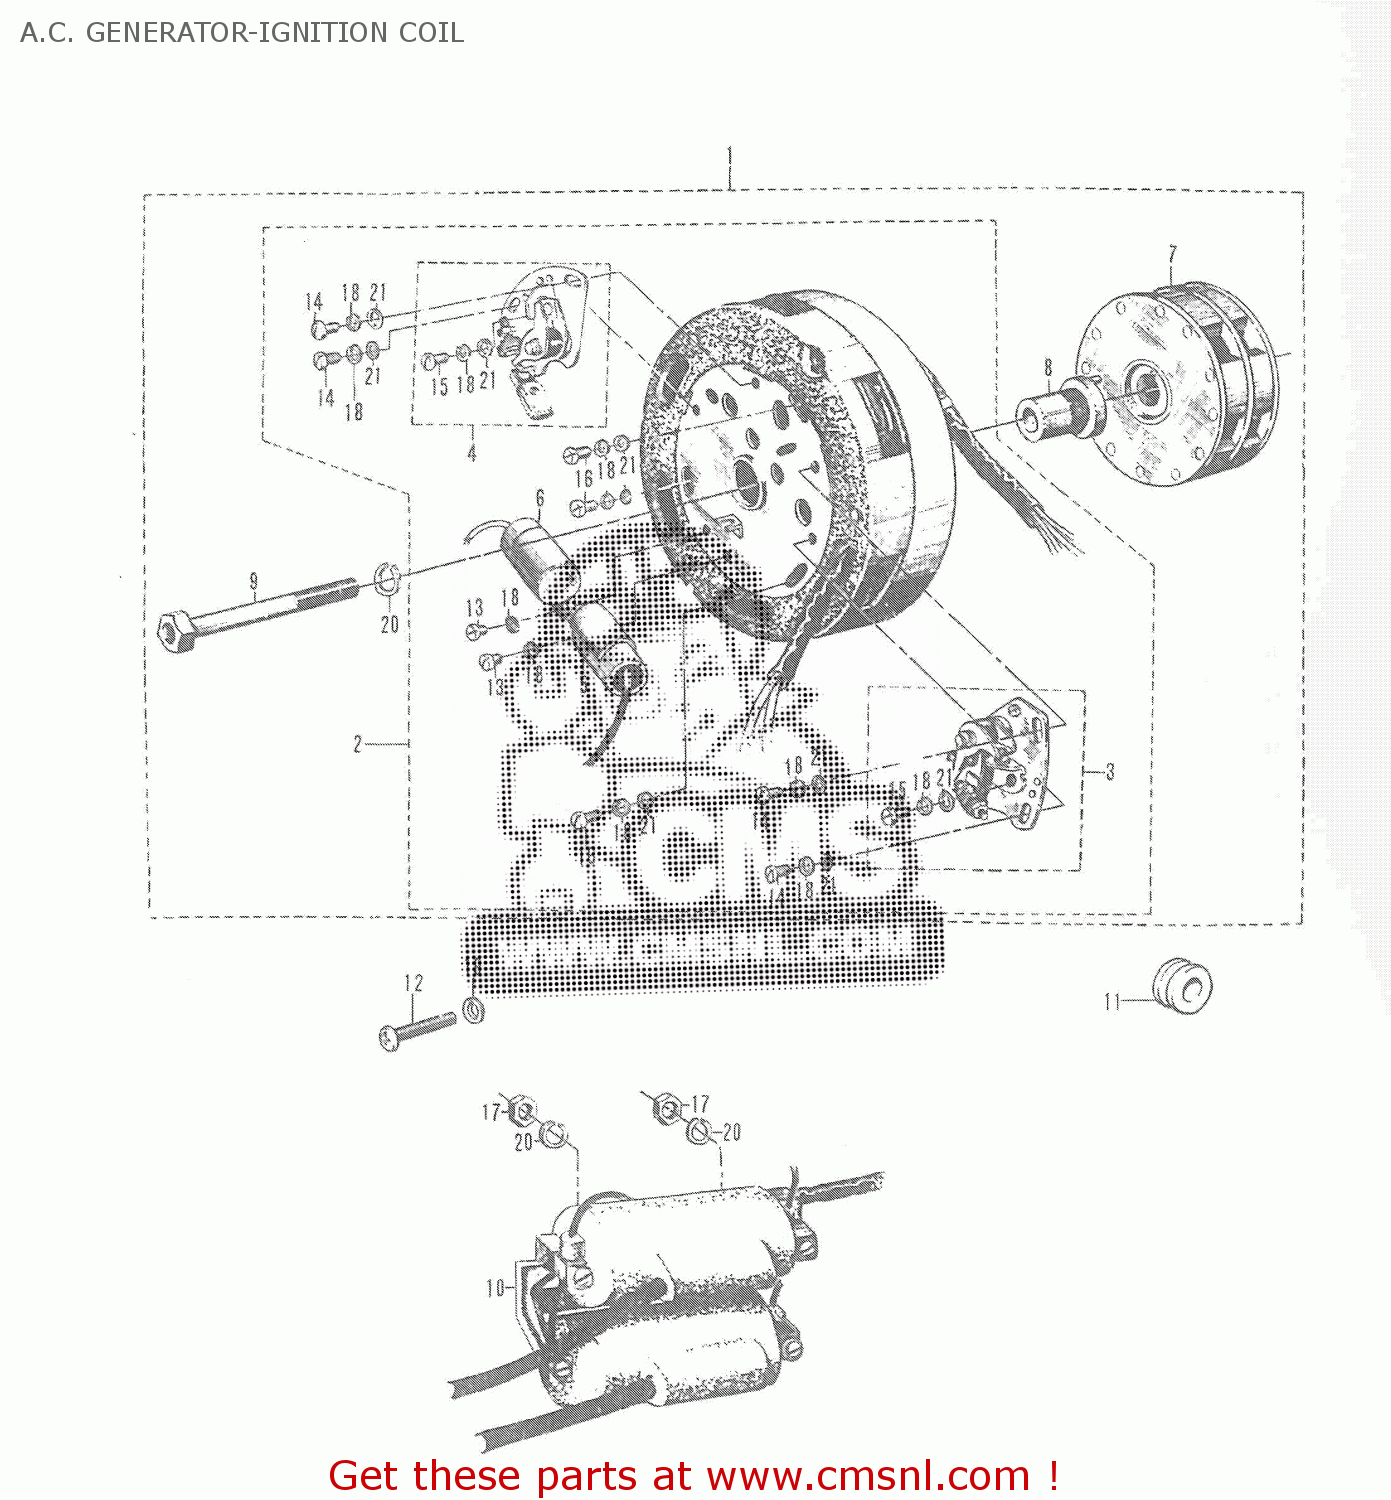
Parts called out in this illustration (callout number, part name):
1	A.C. GENERATOR ASS'Y
2	STATOR ASS'Y
3	RIGHT CONTACT POINT ASS'Y
4	LEFT CONTACT POINT ASS'Y
5	CONDENSER
6	CONDENSER
7	ROTOR
8	CAM,CONTACT BREAKER
9	ROTOR FITTING BOLT
10	COIL ASSEMBLY,IGNITION
11	GROMMET
12	STRONG CROSS HEAD SCREW
13	4X4 SCREW
14	SLOTTED PIN HEAD SCREW
15	SLOTTED PAN HEAD SCREW
16	SLOTTED PAN HEAD SCREW
17	SMALL HEXAGON NUT
18	LOCK WASHER
19	LOCK WASHER
20	LOCK WASHER
21	FLAT WASHER
